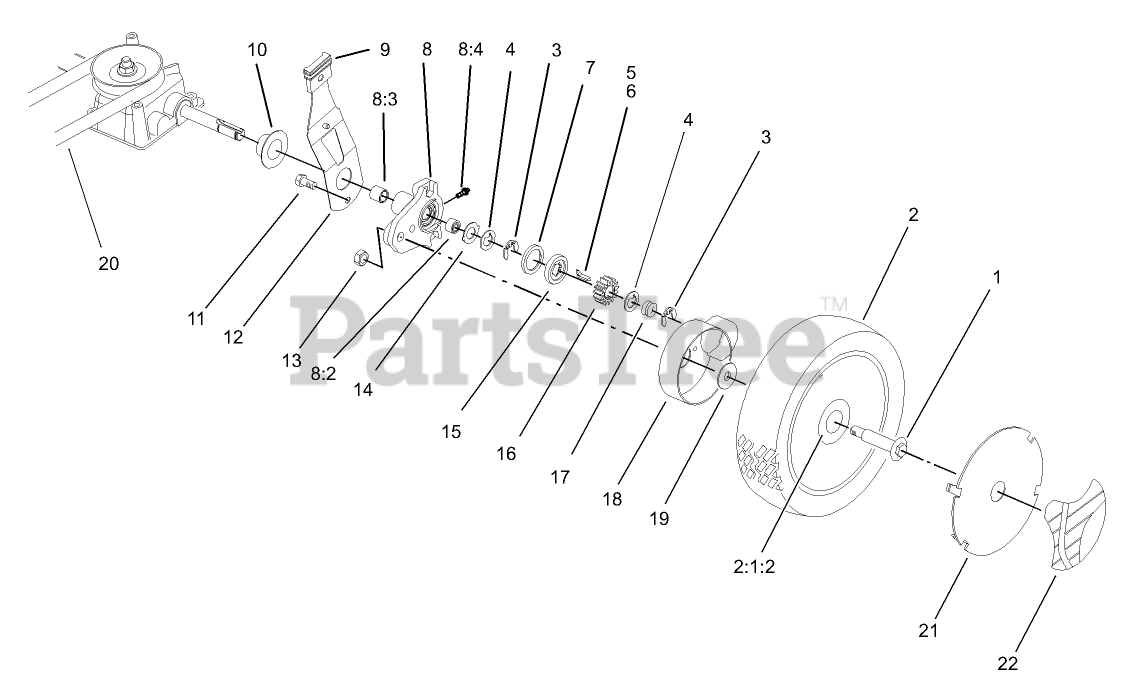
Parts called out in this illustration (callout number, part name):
1	BOLT-SHOULDER
2	WHEEL ASM
2:1	Wheel ASM
2:1:2	BUSHING
3	RING-RETAINING,CLIP
4	WASHER-THRUST, KEYED
5	KEY-ROCKING, RH
6	KEY-ROCKING, LH
7	RING-FRICTION
8	PIVOT ARM ASM
8:2	BUSHING
8:3	BUSHING
8:4	FITTING-GREASE
9	KNOB-ARM
10	CAP-END
11	SCREW-HWH
12	SPRING ARM ASM
13	LOCKNUT
14	WASHER-ARM, PIVOT
15	WASHER-CLUTCH
16	GEAR-PINION
17	SPRING-COMPRESSION
18	COVER-WHEEL
19	SPACER-COVER, WHEEL
20	BELT-V
21	COVER-WHEEL
22	LABEL-WHEEL, SMART
